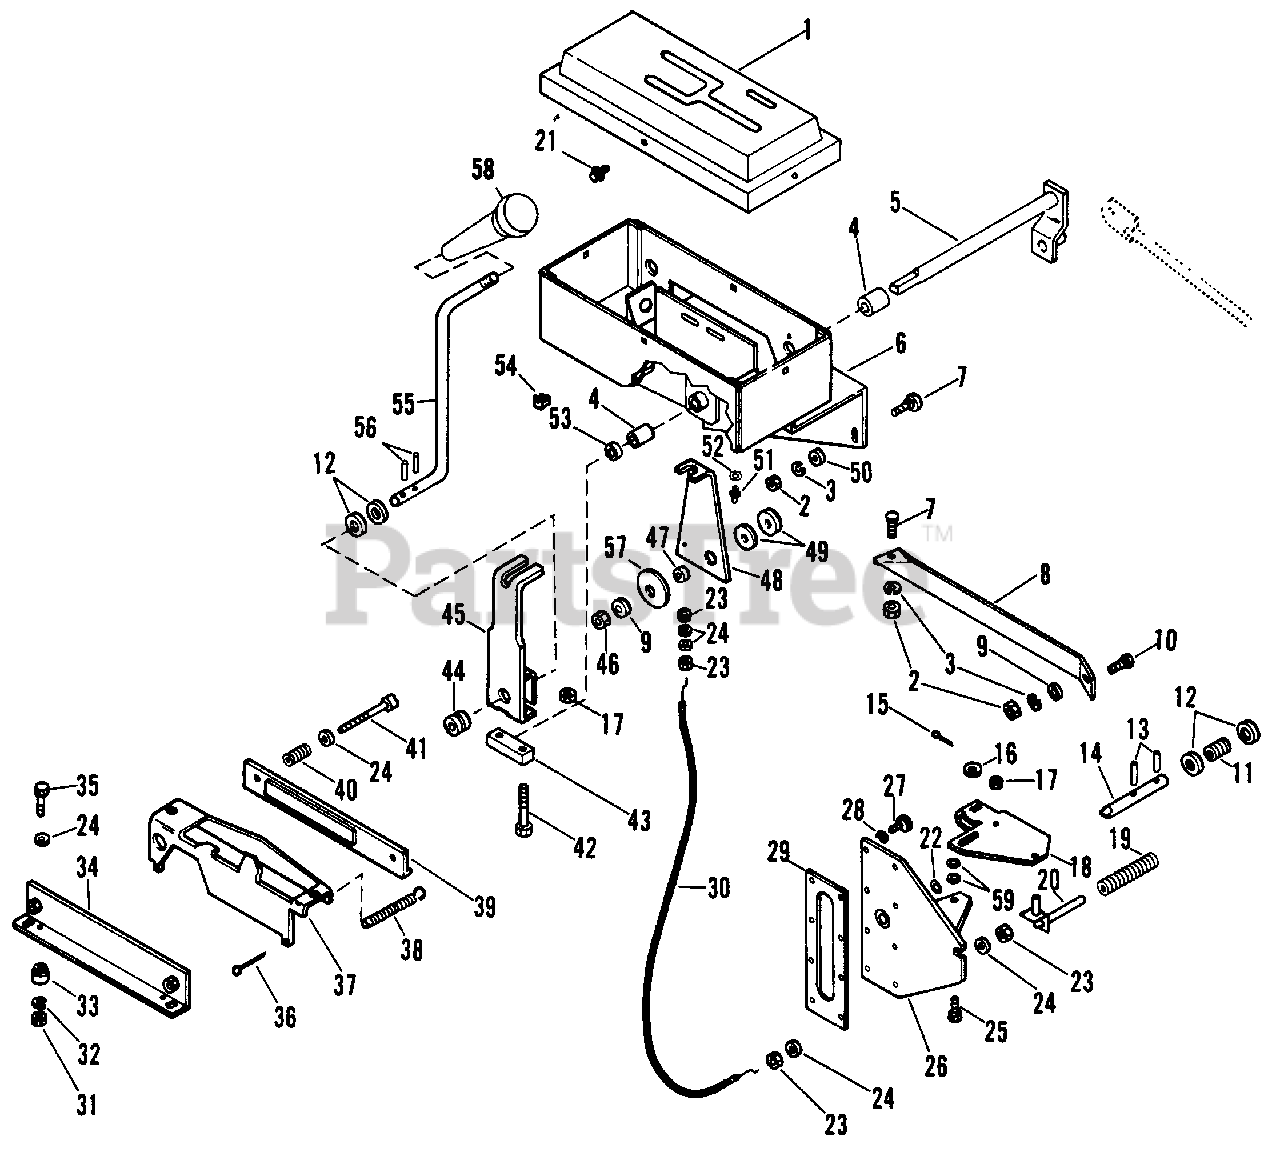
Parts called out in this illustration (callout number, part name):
1	Control Console
2	Nut, Hex 3/8-16
3	Washer, Lock 3/8 Reg.
4	Bushing, Sleeve .625 x .75 x 1.00
5	Shift Shaft
6	Control Box
7	Bolt, 3/8-16 x 1.00 Rd Hd Sq Nk
8	Brace
9	Washer, Flat .406 x .812 x .065
10	Bolt, Hex 3/8-16 x .75
11	Spring, Comp. 3/4 Free Length
12	Washer, Flat .500 x 1.250 x .083
13	Pin, Spring .187 x 1.250
14	Lock Pin
15	Pin, Cotter .125 x .75
16	Washer, .339/.359 x 1.375 x 14 Ga.
17	Nut, Lock 5/16-18
18	Lock Pivot Plate
19	Spring, Comp. 3-1/8 Free Length
20	Pivot Pin
21	Screw, Tapping 10-12 x .50 PHD
22	O-Ring, 1/2 Nom. I.D.
23	Nut, Jam 5/16-24
24	Washer, Flat .312 x .734 x .065
25	Bolt, Hex 5/16-18 x .75
26	Lock Pin Guide
27	Taptite, M5 x 0.8 x 16 HFLPL
28	Washer, Lock Ext. #12 I.D.
29	Gasket
30	Cable
31	Nut, Hex 5/16-18
32	Washer, Lock 5/16 SP
33	Spacer
34	R.H. Friction Brake
35	Bolt, Hex 5/16-18 x 1.25
36	Pin, Cotter .09 x .75
37	Shift Lock
38	Spring, Ext. 2-3/4 Free Length
39	L.H. Friction Brake
40	Spring, Comp. 1-1/2 Free Length
41	Screw, Mach. 5/16-18 x 2.75 Rd
42	Bolt, Hex 5/16-18 x 1.50
43	Strap
44	Grommet
45	Lever
46	Nut, Lock 3/8-16
47	Bushing, Sleeve .375 x .625 x .250
48	Arm
49	Washer, .438 x 1.125 x .188
50	Washer, Flat .438 x 1.000 x .083
51	Fitting, Lube 1/4-28
52	Washer, Lock Ext. 1/4 I.D. Hi-Collar
53	Washer, Flat .640 x 1.005 x .062
54	Plastic Grommet
55	Rod, Shift
56	Pin, Spring .187 x .875
57	Belleville Washer
58	Knob
59	Washer, Flat .375 x .734 x .065
